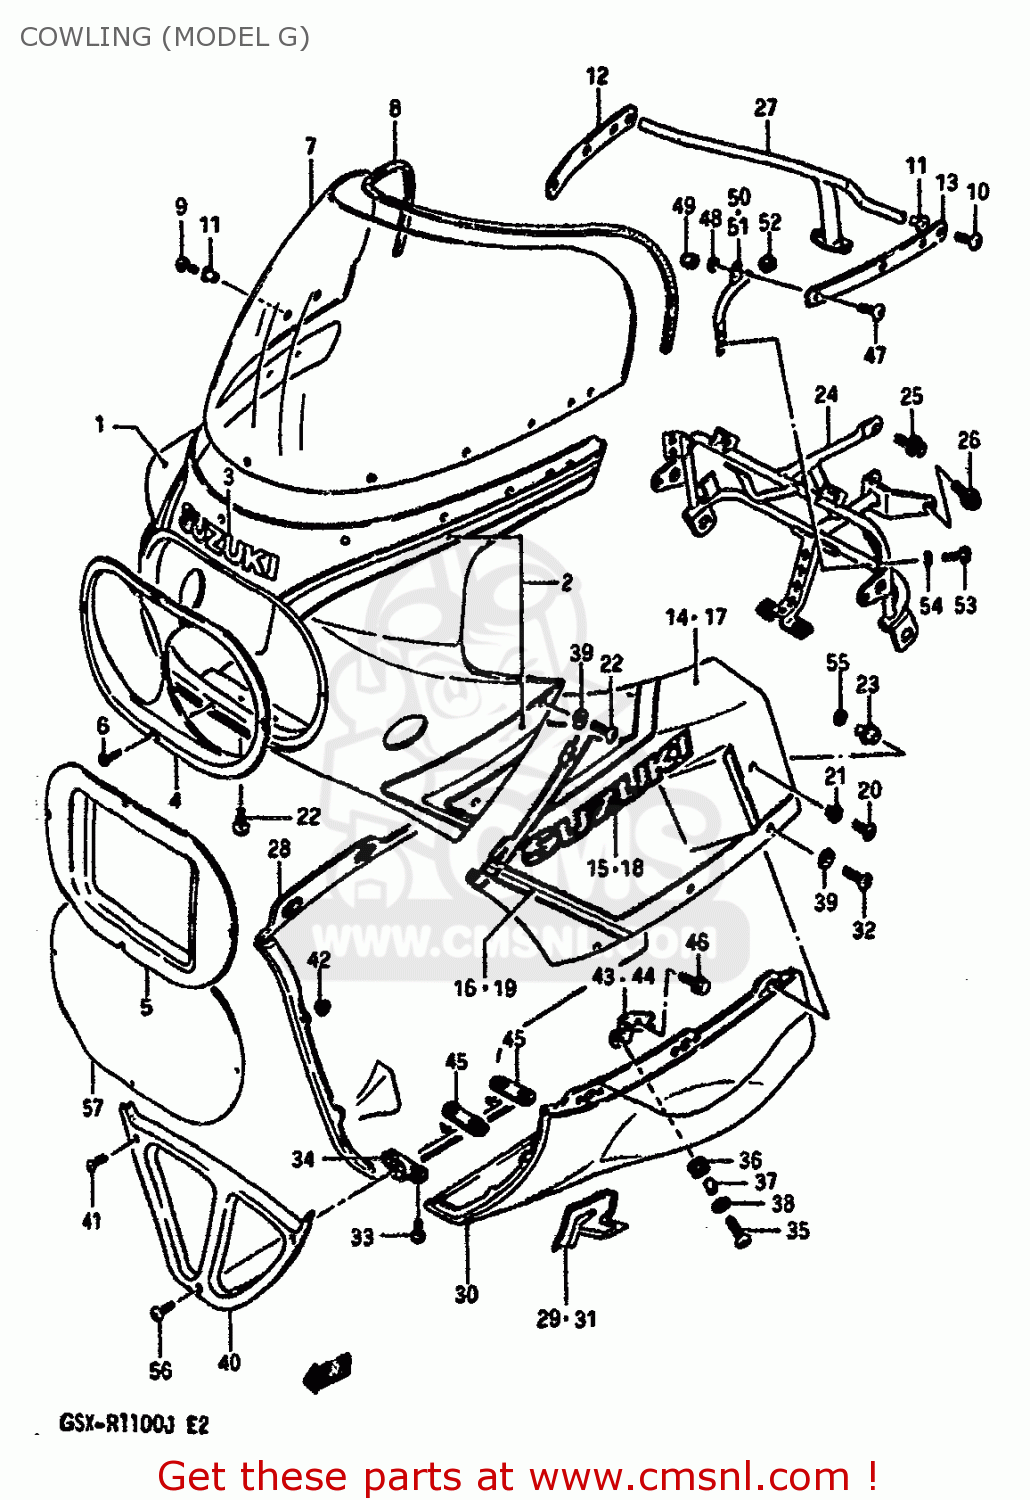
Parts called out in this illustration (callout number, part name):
1	BODY SET,COWLING
2	TAPE SET,BODY COWLING
3	EMBLEM,LEG SHIELD
4	COVER,COWLING FR
5	COVER,FRONT (BLUE)
6	SCREW
7	WINDSCREEN
8	MOLDING
9	SCREW(5X14)
10	SCREW(5X18)
11	NUT,COWLING SCREEN
12	PLATE,RR VIEW MIRROR,R
13	PLATE,RR VIEW MIRROR,L
14	COVER,COWLING SIDE,RIGHT
15	EMBLEM
16	TAPE SET,COWLING SIDE,RIGHT
17	COVER,COWLING SIDE,LEFT
18	EMBLEM
19	TAPE SET,COWLING SIDE,LEFT
20	SCREW(6X12)
21	WASHER
22	SCREW(6X16)
23	CUSHION,COWLING
24	BRACE,COWLING FR
25	BOLT
26	BOLT
27	BRACE,COWLING BODY RR
28	COVER,COWLING,LOWER,RIGHT
29	EMBLEM
30	COVER,COWLING
31	EMBLEM
32	SCREW(6X16)
33	SCREW(6X16)
34	BRACE,COWLING LWR COVER
35	SCREW(6X20)
36	CUSHION
37	SPACER
38	WASHER(6.5X18X1)
39	WASHER
40	COVER,COWLING,LOWER,FRONT
41	SCREW(5X14)
42	NUT
43	BRACE,COWLING LWR,R
44	BRACE,COWLING LWR,L
45	BRACE,COWLING LWR COVER RR
46	BOLT
47	SCREW(6X16)
48	WASHER,LOCK
49	NUT 6MM
50	BRACE,MIRROR,R
51	BRACE,MIRROR,L
52	PLUG(OD:12)
53	BOLT 6X16
54	WASHER,LOCK
55	WASHER
56	SCREW(6X16)
57	COVER,HEADLAMP
